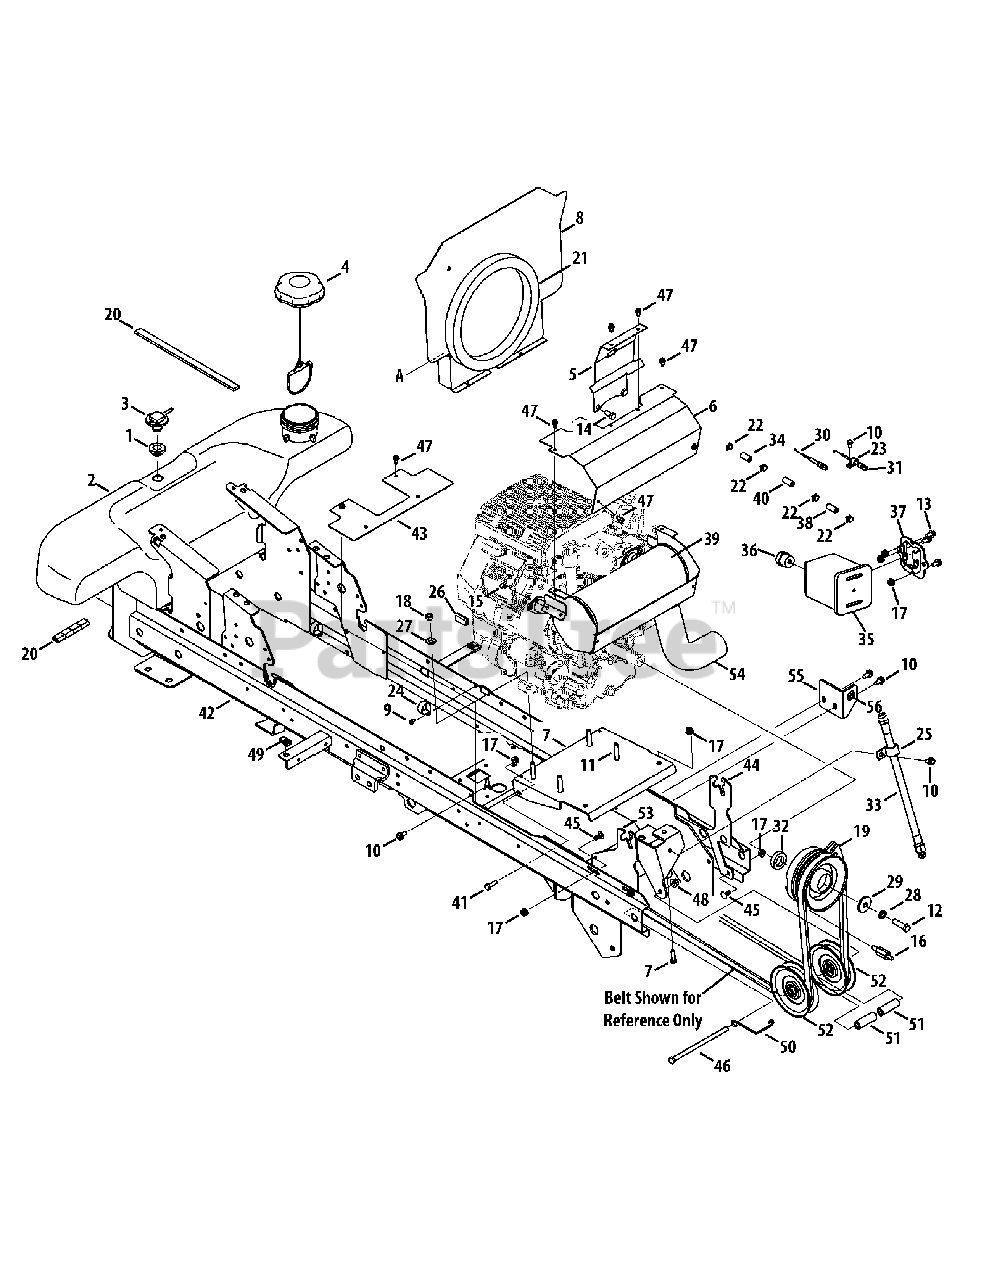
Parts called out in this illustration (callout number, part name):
1	Rubber Grommet, 23.0 x 3.55
2	Fuel Tank
3	Fuel Rollover Valve
4	Fuel Cap, 3.50
5	Clutch Heat Shield
6	Engine Upper Shield
7	Engine Mount Bracket
8	Engine Baffle Plate
9	AB Screw, #10-16 x .500
10	Hex Washer Screw, 5/16-18 x .750
11	Hex Screw, 3/8-24 x 1.75
12	Hex Screw, 7/16-20 x 1.50
13	Hex Screw, 5/16-180 x 1.50
14	Hex Screw, 3/8-16 x .750
15	Hex Screw, M6-1.0 x 10
16	Clutch Stop Stud
17	Flange Lock Nut, 5/16-18
18	Hex Lock Nut, 3/8-24
19	Clutch (GT Models)
19	Clutch (GTX Models)
20	Tape Foam, .75 x .25
21	Intake Gasket Foam
22	Hose Clamp
23	Clamp, 9/16
24	Hose Clamp, 1.0
25	Clamp, 1.0
26	Trim Strip
27	Spring Washer, .401 x .870 x .060
28	Lock Washer, 7/16
29	Flat Washer, .45 x 1.5 x .172
30	Choke Control Cable
31	Throttle Control Cable
32	PTO Spcr., 1.00 x 1.62 x .4 (GT Models)
33	Oil Drain Hose
34	Low Permeation Fuel Hose
35	Carbon Canister
36	Canister Vent Filter
37	Canister Adapter Bracket
38	Low Permeation Fuel Hose
39	Twin Muffler
40	Vent Hose
41	Hex Screw, 5/16-18 x 1.00
42	Frame (GT Models)
43	Lower Baffle
44	Hood Pivot Bracket
45	Carriage Bolt, 5/16-18 x .750
46	Hex Screw, 3/8-16 x 7.25
47	Hex Washer Screw, 1/4-20 x .500
48	Flange Lock Nut, 3/8-16
49	U-Nut, 5/16-18
50	Belt Guide
51	Idler Spacer, .41 x .875 x 2.19
52	Idler Pulley
53	Hood Tilt Bracket
54	Pipe Assembly Heat Shield
55	Exhaust Bracket
56	Grommet, .875 OD x .375 ID x .188
